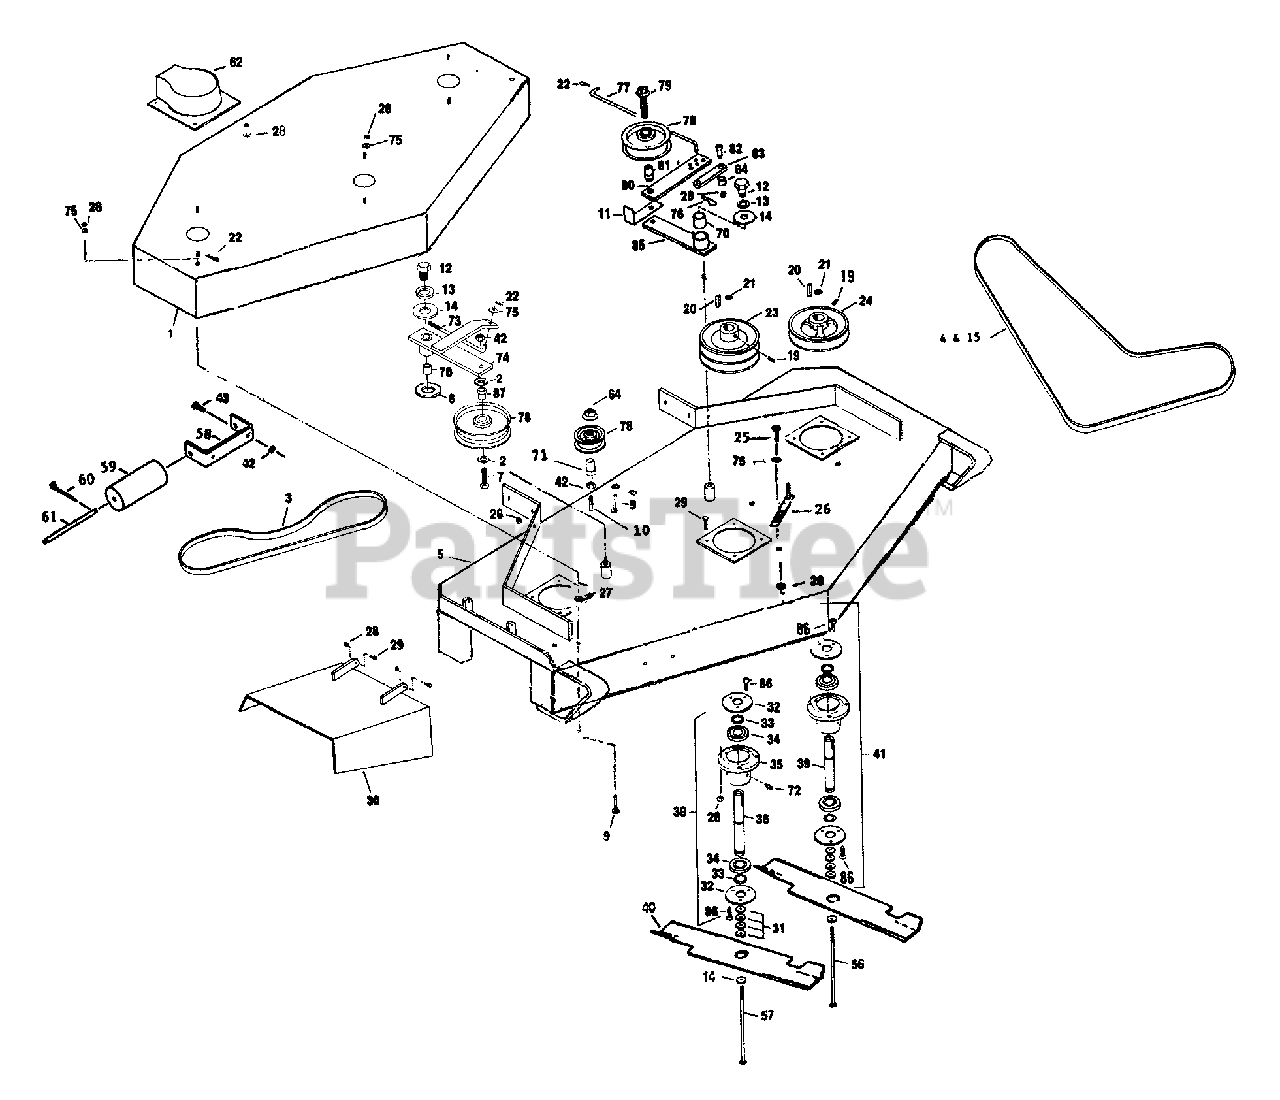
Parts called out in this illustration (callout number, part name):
1	Belt Shield w/Decal
2	FW, .438X1X.084 YZ
3	Belt
4	Belt, 93.3" EL HB (12 H.P. & 12.5 H.P. Eng. Only)
5	Front Deck w/Decals
7	3/8"-16x2" Hex Hd. Cap Screw-Grade 5
9	5/16"-18x3-1/4" Hex Hd. Tap Bolt-Grade 5
10	3/8"-16x2-1/2" Hex Hd. Tap Bolt
11	Belt Snubber
12	5/8"-11x1" Hex Hd. Cap Screw
13	5/8" Lock Washer
14	5/8" SAE Washer
15	HB 89" O.D. Belt (14 H.P. Engine Only)
19	5/16"-18x3/8" Nyloc Knurled Cup Point Set Screw
20	1/4" Sq. x 1-1/4" Machine Key
21	5/8"-18 Regular Hex Nut
22	#2 Hairpin Cotter
23	Pulley, Taper Lock Kit
24	Pulley w/Set Screws (P/N 76956)
25	5/16"-18x3/4" Hex Hd. Cap Screw
26	Belt Guide
27	5/16"-18 Whizlock Nut
28	5/16"-18 Nyloc Hex Nut
29	5/16"-18x1" Hex Hd. Cap Screw
30	Chute Assembly
31	Blade Spacer
32	Cutter Housing Cap
33	Snap Ring
34	Cutter Housing Bearing
35	Cutter Housing
36	Cutter Spindle
38	Center Cutter Housing Assembly
39	Cutter Spindle
40	(.164") Ultra High Lift Blade-16" Long
40	BLADE, 16-1/4" (.250" Ultra High Lift)
41	Cutter Housing Assembly-Complete
42	3/8"-16 Nyloc Hex Nut
43	3/8"-16x1" Hex Hd. Cap Screw-Grade 5
56	5/8"-18x7-1/2" Hex Hd. Cap Screw-Grade 5
57	5/8"-18x8" Hex Hd. Cap Screw-Grade 5
58	Roller Bracket-"U"
59	Roller 3" (NLA)
60	1/8"x1-1/2" Cotter Pin
61	Axle (NLA)
62	Shaft Guard
64	3/8"-16 Whizlock Nut
70	Oilite Bearing
71	Idler Flange Bushing
72	1/8" NPT Straight Zerk
73	Belt Tension Rod
74	Idler Arm-Right w/Brg (P/N 76452)
75	5/16" Std. Flat Washer
76	#4 Hairpin Cotter
77	Lower Blade Drive Linkage
78	Heavy Duty Idler Pulley
79	3/8"-16x1-3/4" Whizlock Bolt
80	Tightening Arm
81	Engagement Flange Bushing
82	3/8"x3/4" Knurled Socket Hd. Shoulder Bolt
83	Assist Arm
85	Idler Arm w/Brg (P/N 76452)
86	#10-24x3/8" Pan Hd. Slt. Mach. Screw
87	Idler Flange Bushing
